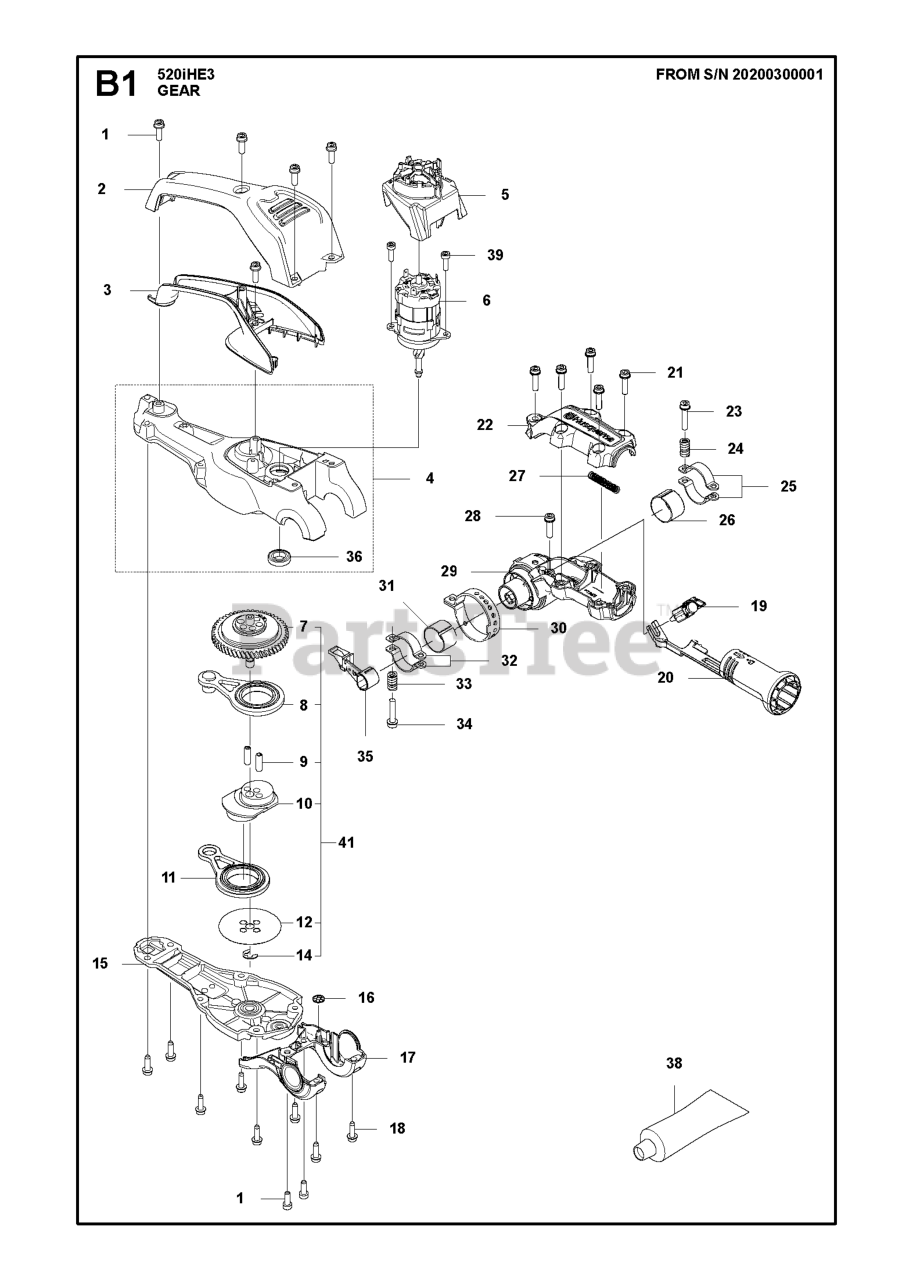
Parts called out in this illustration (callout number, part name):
1	SCREW IHSCFT
3	MOTOR COVER LOWER
5	AIR CONDUCTOR MOTOR
7	GEAR ASSY
9	HEAVY DUTY DOWEL PIN PROJEKT 1
10	ECCENTRIC DISC GEAR
12	WASHER DISK DISC
14	LOCK WASHER
16	LOCK WASHER
17	BEARING CAP
19	LOCKING PIN ASSY
20	HANDLE GRIP
21	SCREW IHSCFT
25	BRAKE BAND ASSY POLE HEDGETRIM
26	SLIDE RING
27	COMPRESSION SPRING
28	SCREW IHSCFT
29	HOUSING JOINT
30	RING INDEX 520IHE3/IHT4
31	SLIDE RING
32	BRAKE BAND ASSY POLE HEDGETRIM
36	BALL BEARING
38	GREASE 20G HEDGE TRIMMER GEAR
39	SCREW ITXSCM
41	GEAR ASSY GEAR ASSY KIT 520IHE
